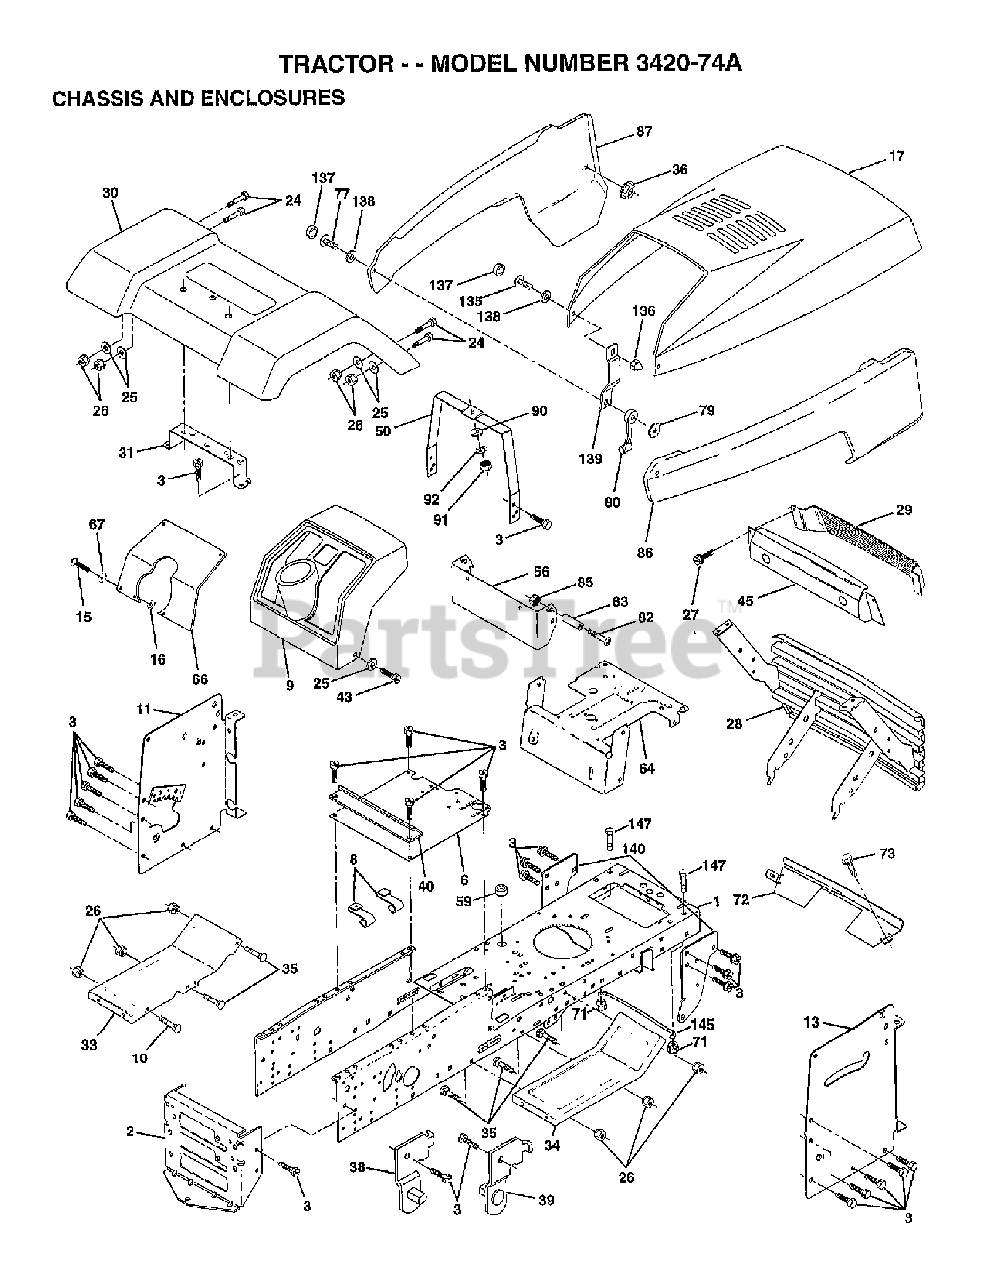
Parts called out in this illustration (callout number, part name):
6	SADDLE FLAT
8	CLIP,INSULATOR
17	Poulan TBD
25	WASHER
26	NUT
30	Poulan TBD
31	BRACKET.SUPPORT.FENDER
33	Poulan TBD
34	Poulan TBD
36	PAL NUT LT
38	BRACKET LH PIVOT
39	BRACKET RH PIVOT
43	SCREW GTV
50	DASH SUPT YP
64	DASH LOWER LT
66	Poulan TBD
67	WASHER
71	NUT.CROWNLOCK.1/4
72	Poulan TBD
73	SCREW CRT
79	NUT.WELD
80	LATCH.HOOD.
82	SCREW
83	SPACER LT
85	NUT **
86	Poulan TBD
87	Poulan TBD
90	WASHER PM
91	NUT
92	LOCKWASHER
135	SCREW 10-24X3/8
136	NUT
137	SNAP CAP LT
138	WASHER LT
139	BRACKET.SUPPORT.HOOD/PANEL.NLA
140	BRACKET SUSPENSION FRONT
147	BOLT.HEX.1/4.X.3/4.DICHROMATE
